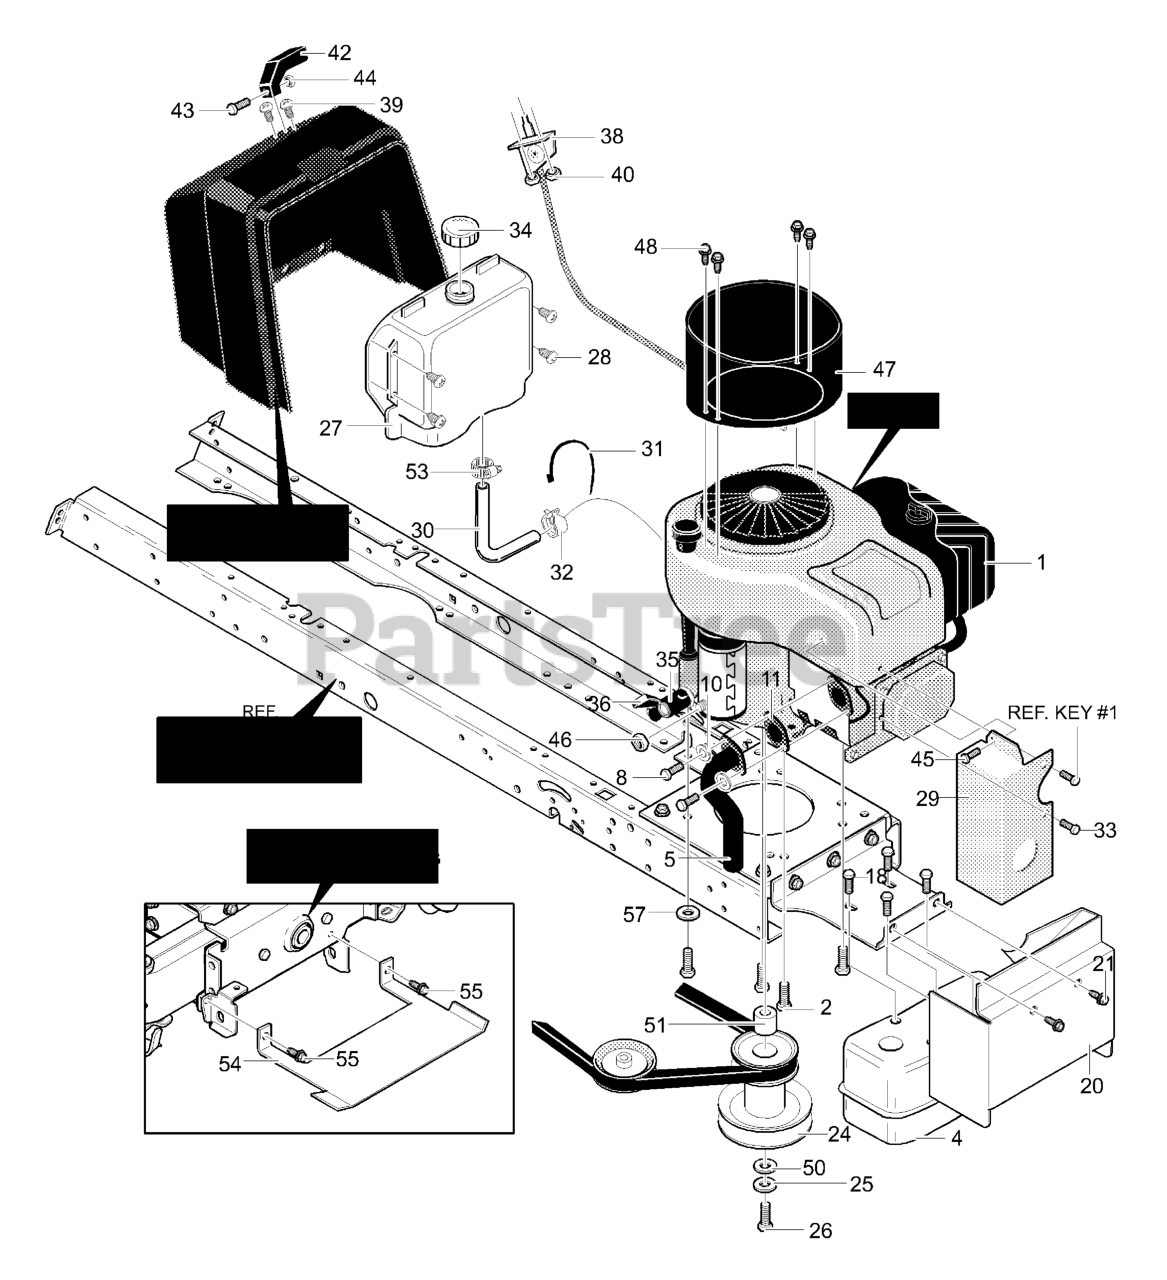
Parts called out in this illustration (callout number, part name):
1	17HP Engine
2	Engine Bolt 3/8x1.25
4	Muffler, Single Cylinder
5	Exhaust Tube
8	Screw, 5/16-18 x 0.75
10	Washer, Hvsptlk
11	GASKET, Exhaust
18	Screw, 1/4-20x.63
20	Heat Shield, Lower Front
21	Screw, 5/16-18 x 0.75
24	Stack Pulley
25	Washer, Regsptlk
26	Screw, 7/16-20
27	Tank, Fuel 2 Gal.
28	Screw, #12x.50
29	Heat Shield Side
30	Gas line 12 Inches
31	Cable Tie
32	Clamp, Fuel
33	Screw, 1/4-20x.50
34	Gas Cap 2.0
35	Oil Drain Valve Assembly
36	Cap, Oil Drain Valve
38	Throttle Control
39	Screw, 10-24x.63
40	Nut, #10-24
42	Knob, Throttle Control
43	Screw, #8-32
44	Nut, #8-32
45	Screw, 10-16x.50 Drill
46	Nut, 1/4-20
47	Plenum
48	Screw, 10-16x.50 Drill
50	Flat washer
51	Spacer, Sleeve
53	Clamp, Hose Screw Type
54	Shield, Anti-Dehydration
55	Screw, 5/16-18 x 0.75
57	Washer, Exlk
